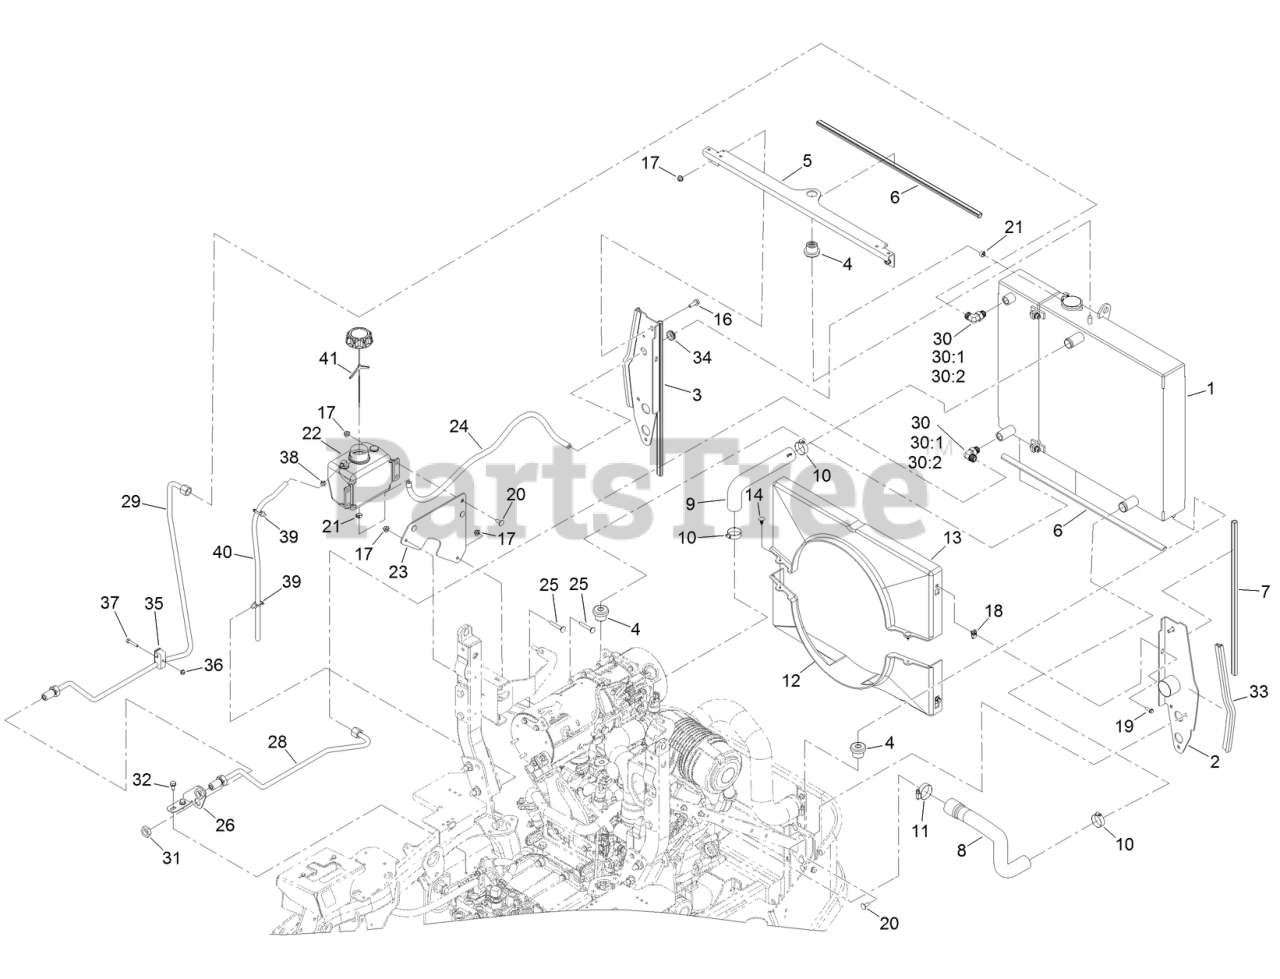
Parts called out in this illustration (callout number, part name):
1	COOLING ASM
2	SUPPORT-RADIATOR, LH
3	SUPPORT-RADIATOR, RH
4	MOUNT-ISOLATOR
5	BRACKET-COOLING, TOP
6	SEAL-BULB
7	SEAL-BULB
8	HOSE-RADIATOR, LOWER
9	HOSE-RADIATOR, UPPER
10	CLAMP-HOSE
11	CLAMP-HOSE
12	SHROUD-BOTTOM
13	SHROUD-TOP
14	PLUG-PLASTIC
16	SCREW-HHF
17	NUT-HF, NI
19	SCREW-HWH
20	SCREW-CARR
21	CLAMP-HOSE
22	TANK-OVERFLOW, W/CAP
23	BRACKET-BOTTLE
25	BOLT-CARR
26	BRACKET-BULKHEAD
28	HYDRAULIC TUBE ASM
29	HYDRAULIC TUBE ASM
30	FITTING-ELBOW, 90 DEG
30:1	O-RING
30:2	O-RING
31	NUT-BULKHEAD
32	SCREW-HWHTF
33	SEAL-BULB
34	GROMMET
35	CLAMP-TWIN
36	NUT-HF
37	SCREW-HH
38	CLAMP-HOSE
39	CLIP-TIE
40	HOSE-FUEL
41	CAP-W/TETHER
